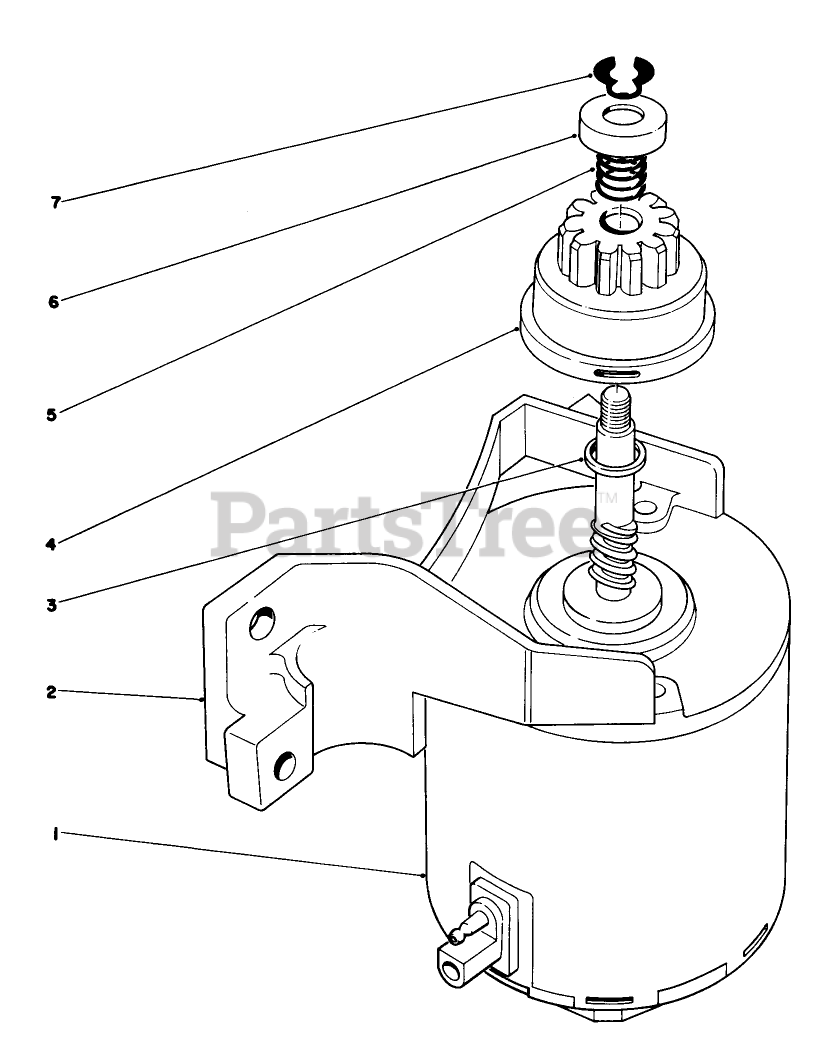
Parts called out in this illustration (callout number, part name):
1	END FRAME W/BRUSH
2	BRKT END FRAME
3	SPACER
4	PINION ASM
5	COMPRESSION SPRING
6	PINION STOP
7	RING-RETAINING
